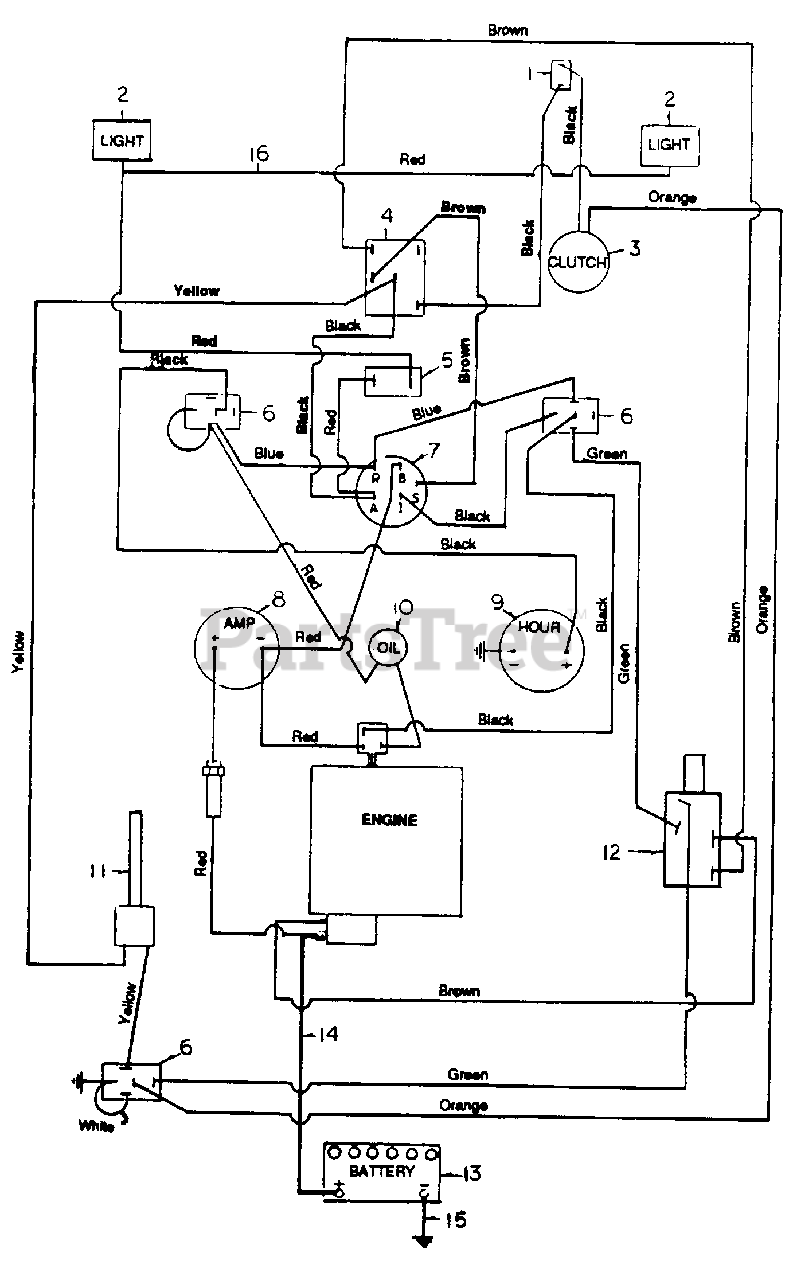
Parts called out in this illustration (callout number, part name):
1	10Amp Circuit Breaker
2	Headlight Assembly
3	Electric Clutch Assembly
4	PTO Clutch Switch
5	Light Switch
6	Pelay
7	Ignition Switch
13	Battery
16	Wiring Harness
